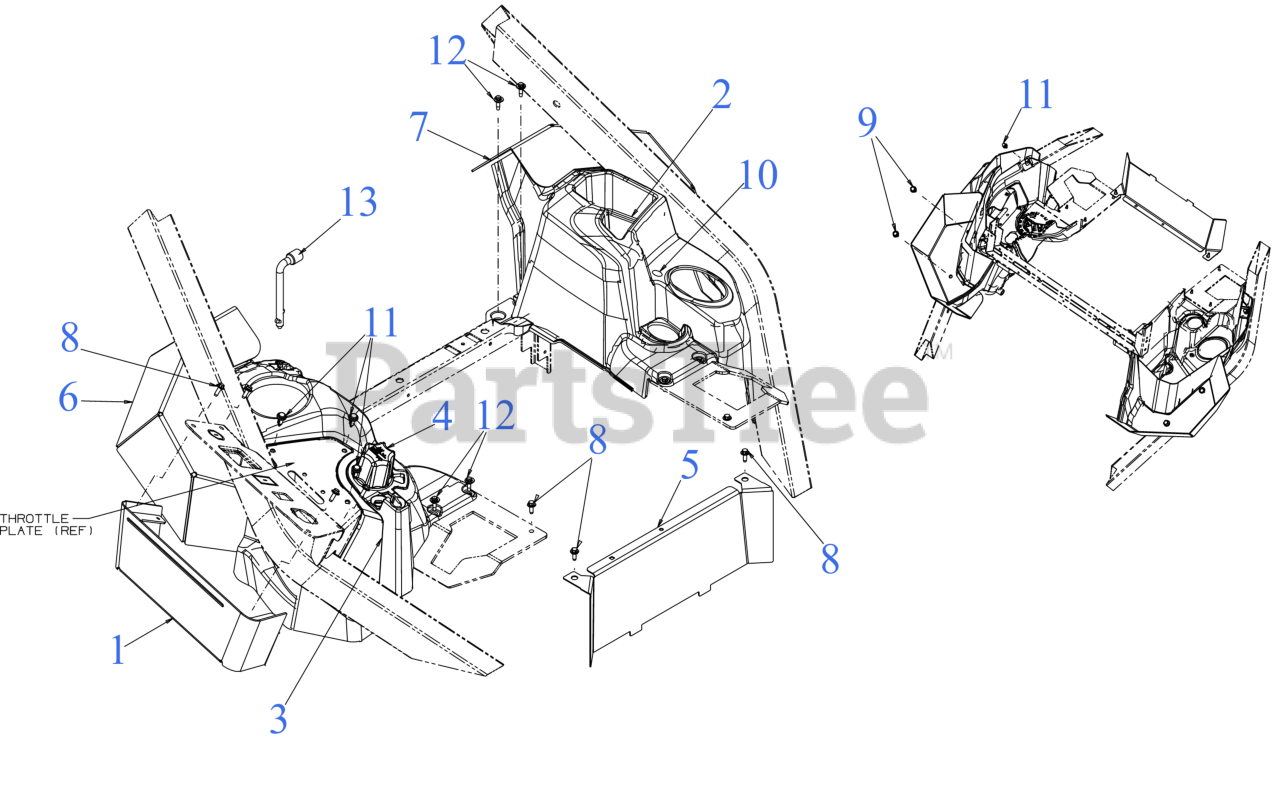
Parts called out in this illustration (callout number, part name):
1	CONTROL PANEL COVER
2	CONSOLE (LH)
3	CONSOLE (RH)
4	DECK HEIGHT ADJUSTMENT KNOB
5	SEAT BOX FRONT PLATE
6	FENDER (REAR) (RH)
7	FENDER (REAR) (LH)
8	SCREW M6-1 x .625
9	SCREW 3/8-16 x 3/4
10	RATCHET CLIP
11	PLASTIC RIVET
12	SHOULDER SCREW M6-1 .368 X.115
13	MULTI TOOL 1/2" SOCKET
